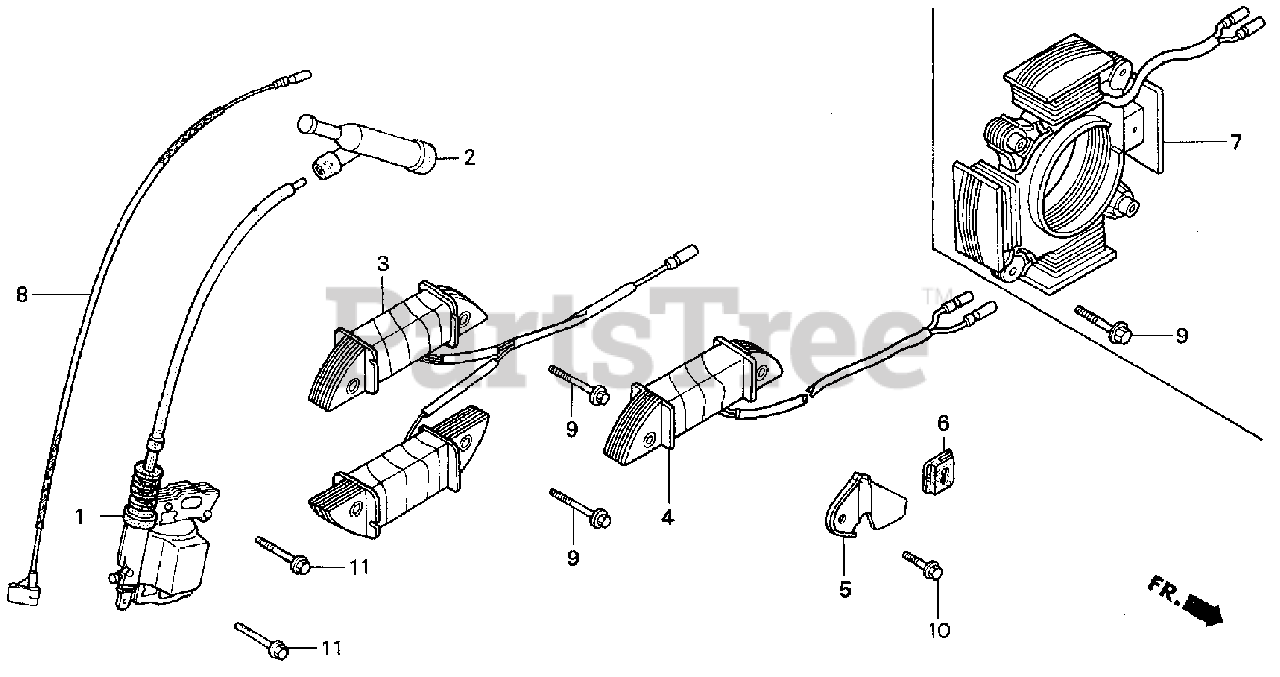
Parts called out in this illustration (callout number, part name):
1	COIL ASSY., IGNITION
2	CAP ASSY., NOISE SUPPRESSOR
8	WIRE, STOP SWITCH (370MM)
11	BOLT, FLANGE (6X25)
